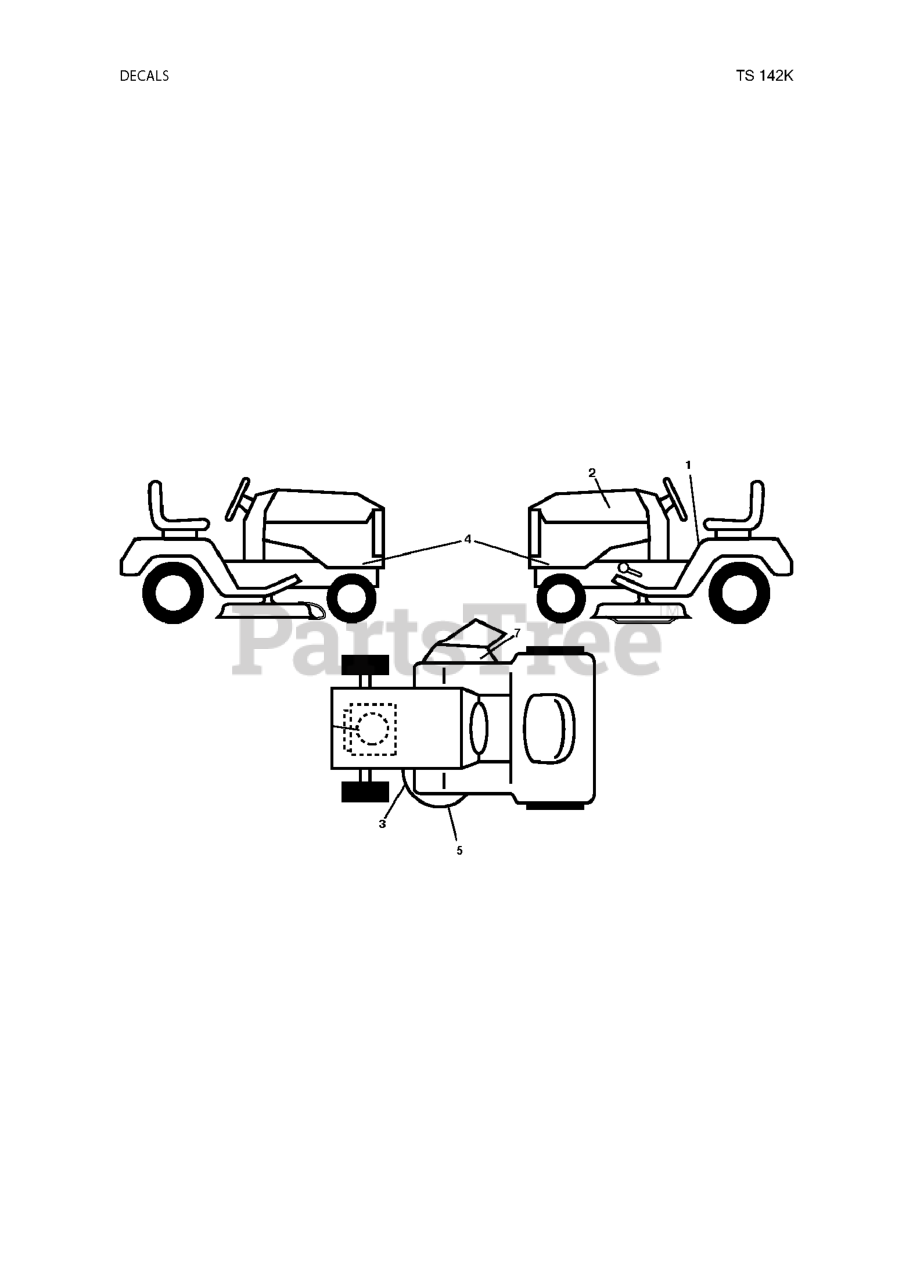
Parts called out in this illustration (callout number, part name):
1	DECAL.WARNING.2007.ENG/FR
3	DECAL.DECK.BELT.ROUTE.42"2021
4	DECAL.SDPNL.HUSQGT.TS142K.SET
5	DECAL.DECK.STAMP.BIOCLIPCMP.HU
7	DECAL.DECK.DEFLECTOR.WARNING
